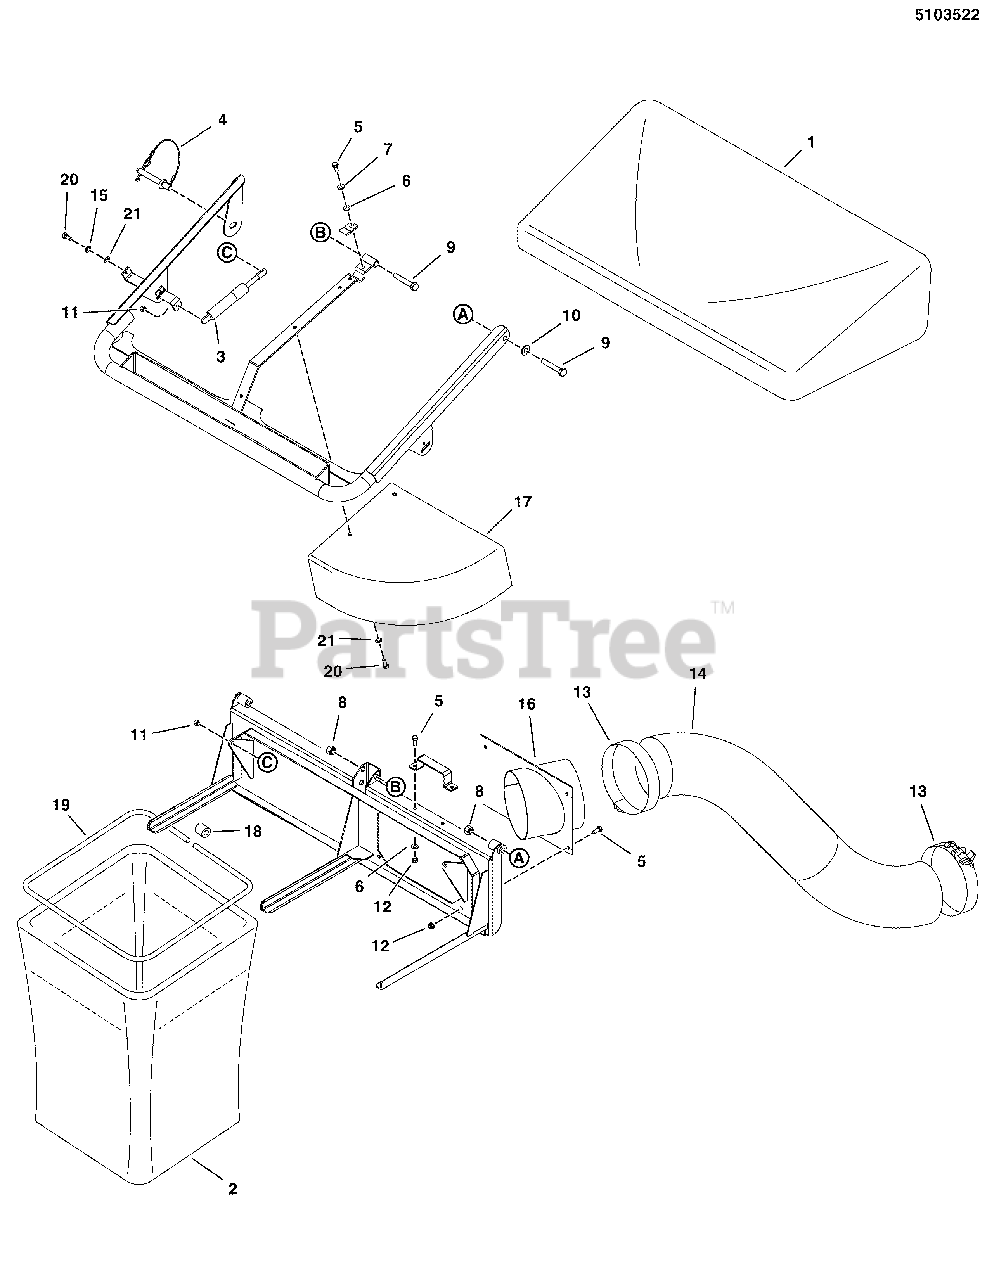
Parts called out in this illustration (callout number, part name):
1	2-BAG AIR DOME
2	CATCHER BAG W/ HANDLE
3	GAS CYLINDER
4	DETENT PIN W/ LANYARD
5	BOLT, 5/16-18 X 3/4 GD5
6	WASHER, 5/16" SAE
7	WASHER, 5/16 LOCK CZ
8	NUT, 1/2-13 HEX NYLON LOCK
9	BOLT, 1/2-20 X 3" GD5
10	WASHER, 1/2 SAE
11	NUT, 5/16-18 HEX NYLON LOCK
12	NUT, 5/16-18 HEX NYLOCK FLANGE
13	CLAMP, 6" UPPER & LOWER, COLLECTORS
14	HOSE, FLEXIBLE, 6" DIA X 54"
15	WASHER, 1/4 LOCK
16	WELD, INLET, 6.0, 2-BAG - BLK
17	WELD, DEFLECTOR - BLK
18	BAG FRAME CONNECTOR, PLASTIC
19	BAG FRAME
20	HHCS, 1/4-20 X 0.625, GR5, ZINC/CLEAR
21	WASHER, 1/4 SAE
